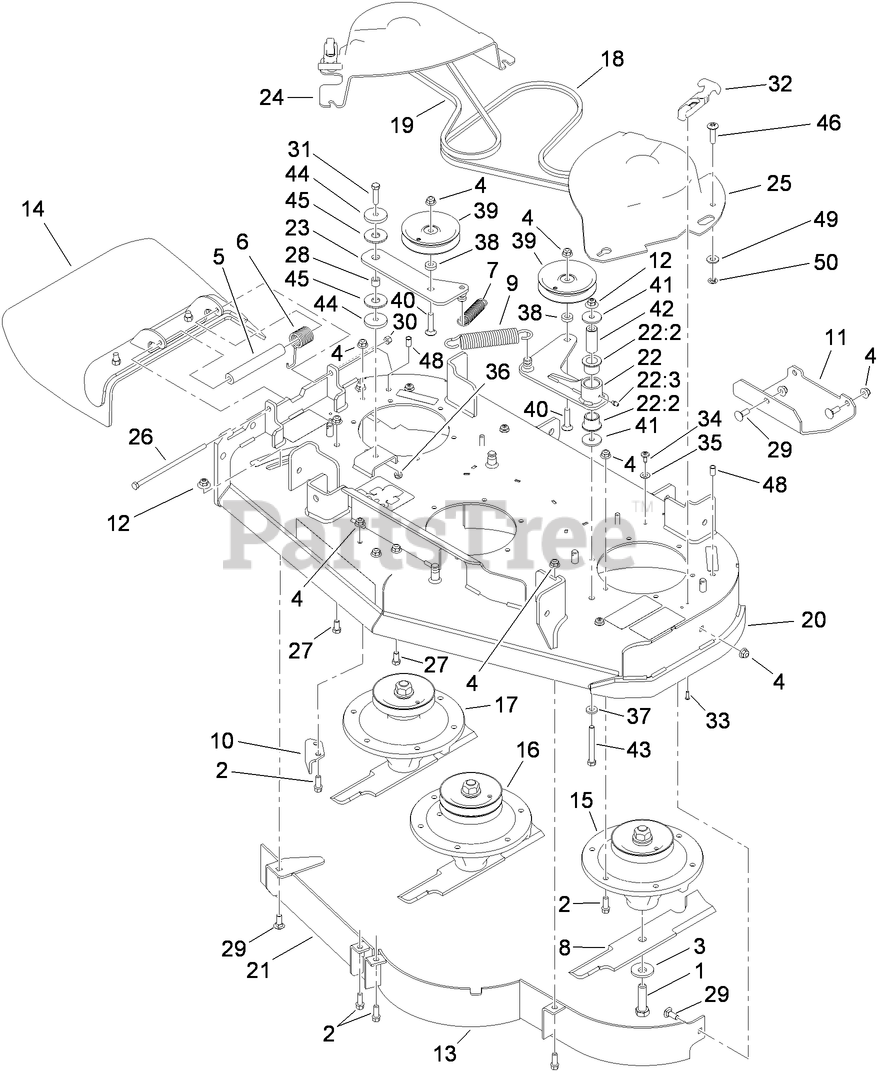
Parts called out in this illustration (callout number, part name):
1	SCREW-BLADE
2	SCREW-HWH
3	Washer-Blade Bolt, Heavy
4	NUT-HF, NI
5	SPACER
6	SPRING-TORSION
7	SPRING-EXTENSION
8	BLADE-14 INCH (HIGH SAIL)
9	SPRING-EXTENSION
10	BAFFLE-DISCHARGE
11	PLATE-SKID
12	NUT-FLANGE, NI
13	BAFFLE ASM
14	DEFLECTOR ASM
15	SPINDLE ASM
16	SPINDLE ASM
17	SPINDLE ASM
18	BELT-V
19	BELT-V
20	DECK ASM
21	FRONT BAFFLE ASM
22	IDLER ARM ASM
22:2	BUSHING
22:3	FITTING-GREASE
23	IDLER ARM ASM
24	COVER-BELT, RH
25	COVER-BELT, LH
26	SCREW-HH
27	SCREW-HH
28	BUSHING-LEVER, LIFT
29	BOLT-CARR
30	NUT-LOCK, NI
31	SCREW-HH
32	LATCH-RUBBER
33	SCREW-HSBH
34	SCREW-SHOULDER
35	WASHER-THRUST
36	NUT-LOCK, NI
37	SPACER
38	SPACER
39	PULLEY-IDLER
40	SCREW-CARR
41	WASHER
42	SPACER-PLAIN
43	SCREW-HH
44	WASHER-PLAIN
45	WASHER-FRICTION, COMPOSITE
46	SCREW-TTH
48	INSERT-NUT
49	WASHER-FLAT
50	NUT-RETAINER
